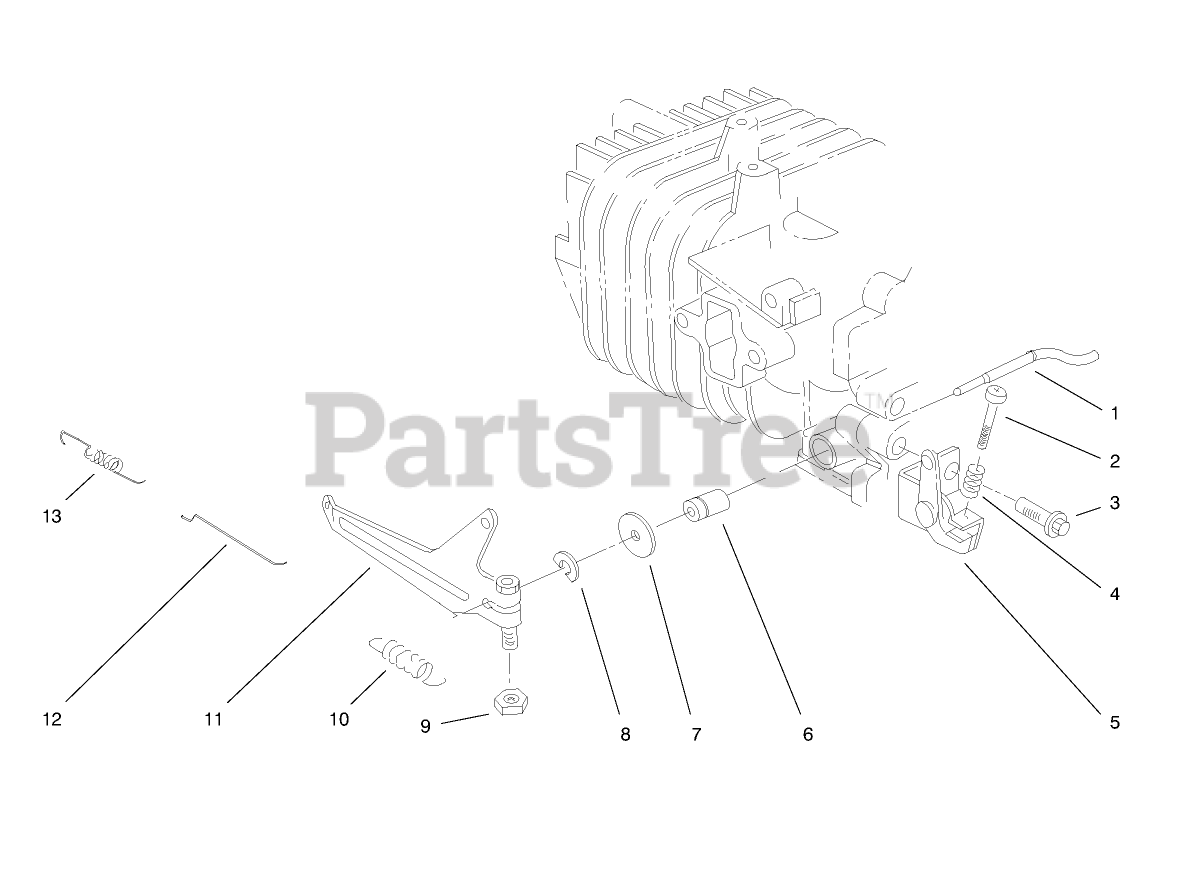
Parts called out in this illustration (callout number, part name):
1	SHAFT
2	SCREW
4	SPRING
5	GOV SPR BRKT
6	SEAL-OIL
7	WASHER
10	GOV SPRING
12	CARB ROD
